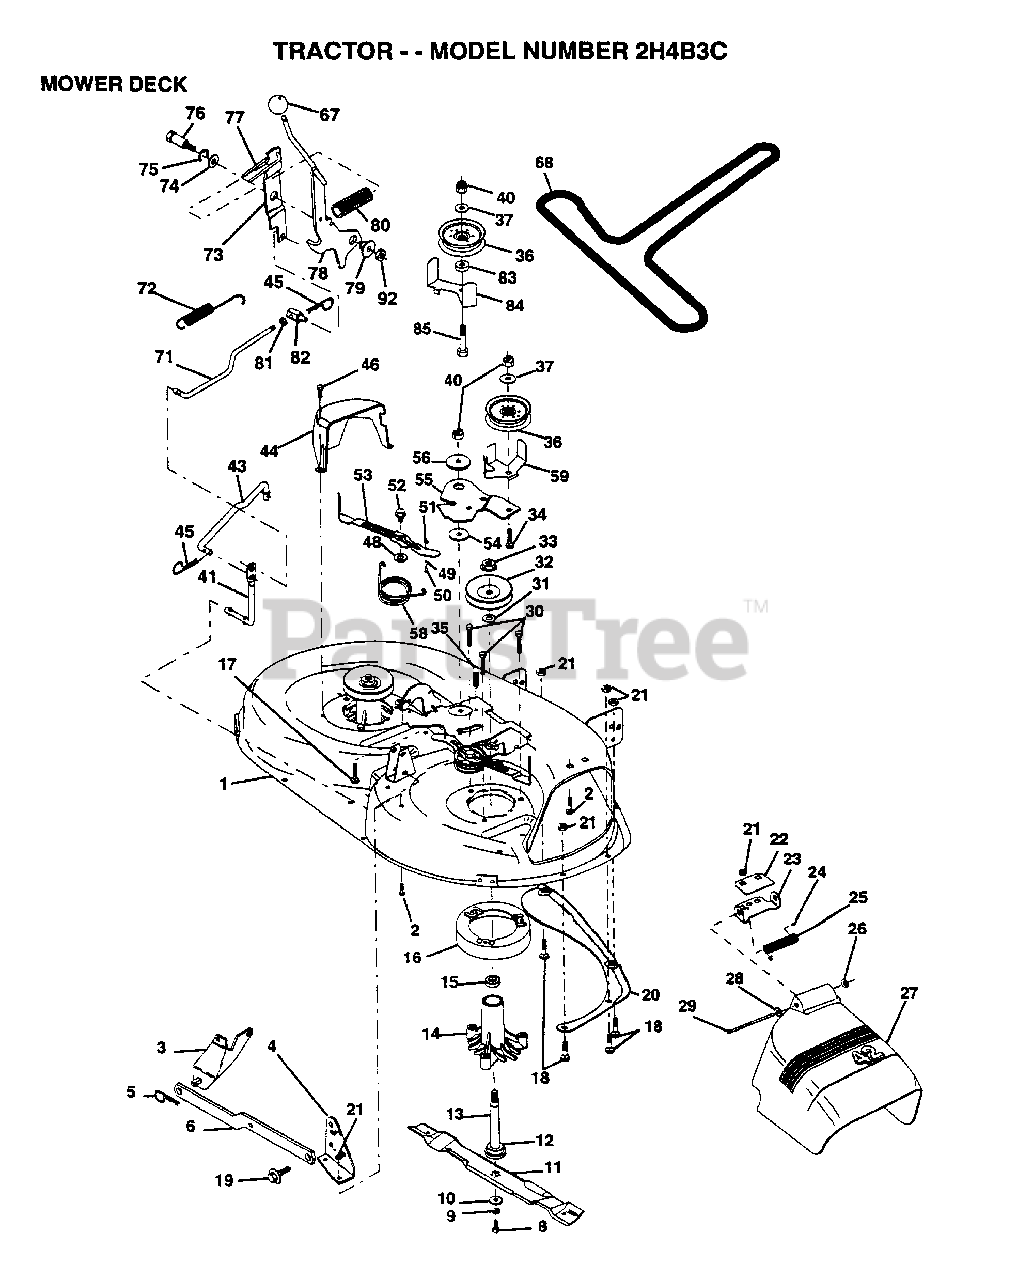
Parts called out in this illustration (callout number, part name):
1	DECK.WELD.42.
2	BOLT
3	BRKT ASM SWAY BAR
4	BRKT DECK SW BAR
8	BLADE BOLT
10	WASHER.HARD.BLADE
11	"BLADE.42"" HIPERF"
12	BEARING.BALL
14	HSG ASM MANDREL
15	BEARING
16	STRIPPER RND MWR
17	BOLT RDHD 3/8-16
18	BOLT
19	BOLT SHD 5/16-18
22	STIFFENER BRKT
23	DEFLECTOR BRKT
24	CAP-SLEEVE LT
25	SPRING TORSION
26	NUT PUSH M
27	DEFLECTOR.SHIELD
28	WASHER
29	HINGE ROD
31	WASHER
34	BOLT
35	XMAS TREE FASTNER
36	FLAT IDLER PULLEY
37	WASHER
41	PIVOT ROD
43	ROD CLUTCH W/NIBS
44	GUARD MAND LH BLK
45	RETAINER M
46	SCREW.1/4-20X5/8
48	HARD SMALL WASHER
50	SHOULDER BOLT
51	LOCKNUT
52	BOLT.SHLD.5/16-18
53	BRAKE PAD ARM ASM
54	HARDENED WASHER
56	SPACER RETAINER
58	SPRING TORSN BRAK
59	GUARD IDLER TUV
67	KNOB T(3/8 HOLE)
68	BELT.V.T-PATH
71	ROD CLUTCH 38/42
72	RETURN SPRING
73	CLUTCH ARM SECOND
74	WASHER
75	RING
76	SHOULDER BOLT
77	SPRING KEEPER
79	BUSHING
81	NUT
82	TRUNION ADJ
83	WASHER
85	BOLT
92	NUT
